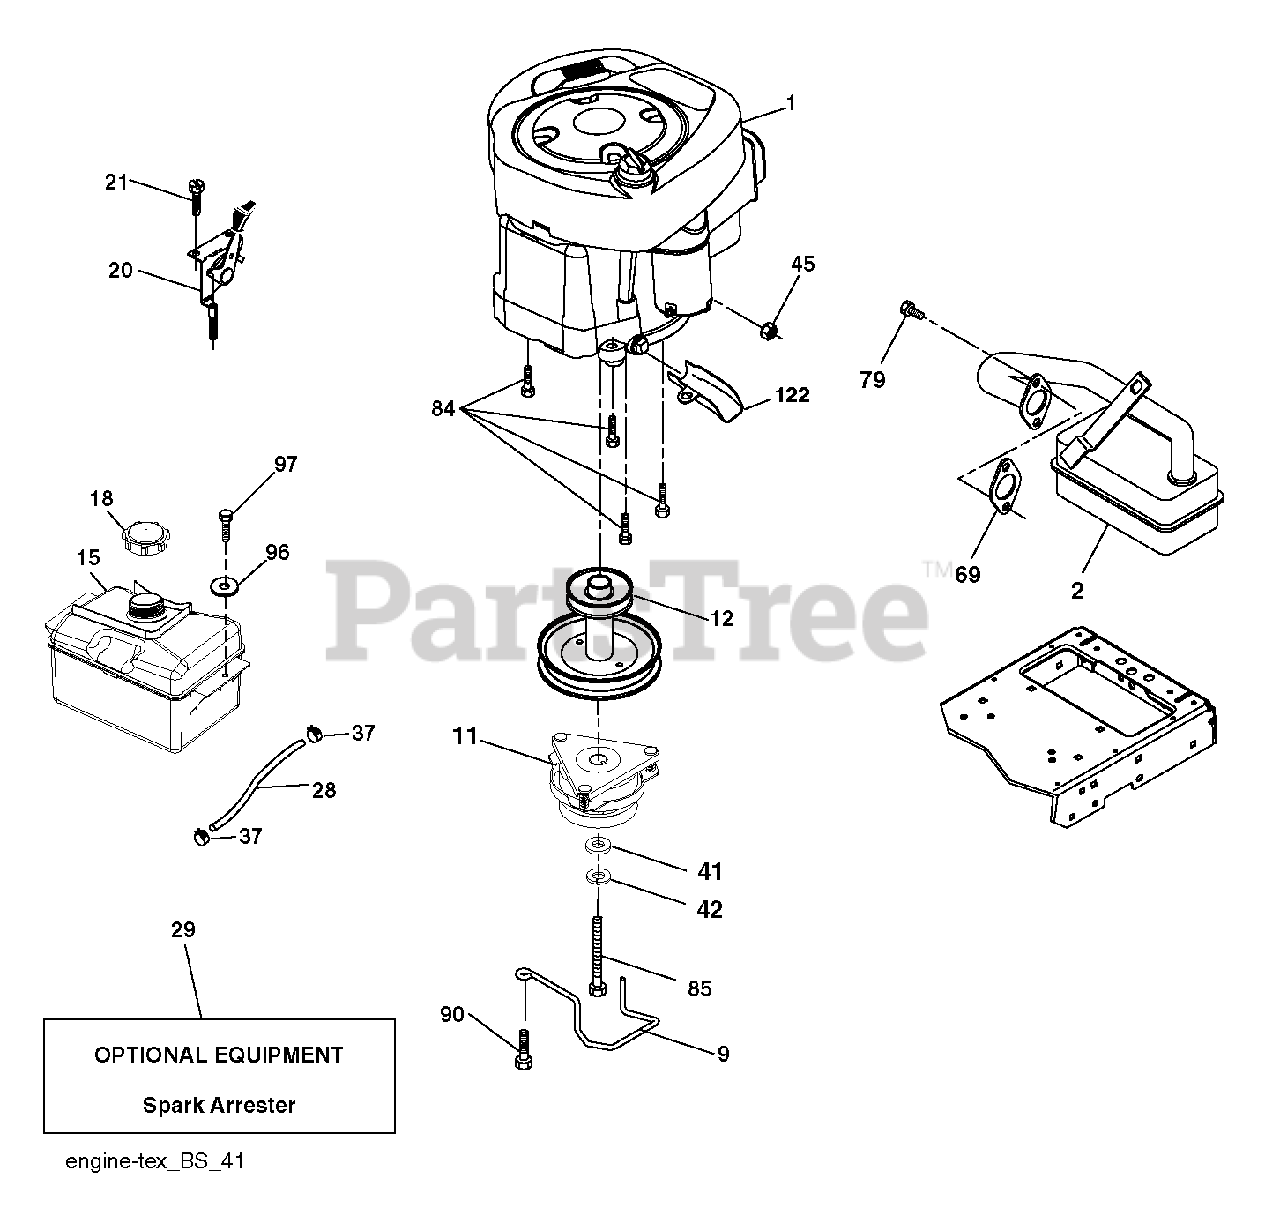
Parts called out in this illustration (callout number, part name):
9	KEEPER.BELT.ENGINE.3.25
11	CLUTCH
12	PULLEY.ASM.ENG.OGURA.3
15	TANK FUEL FRT 1.5 GAL
18	CAP ASM.FUEL.2.25"FR.
20	CONTROL.TH/CK.C.
21	SCREW.#10 X 0.750.BOS THREAD
28	LINE.FUEL.20
29	ARRESTER SPARK (OPTIONAL)
37	HOSE CLAMP
42	LOCKWASHER
45	NUT
69	REPL BY 532 27 22-93
79	SCREW.SOCKET HD.5/16-1
84	SCREW.3/8-16
85	BOLT HEX 7/16-20X4-1/4"
90	SCREW 3/8-16X1
97	SCREW HEXWSHR 1/4-20X3/4
122	EXTENSION DRAIN OIL
